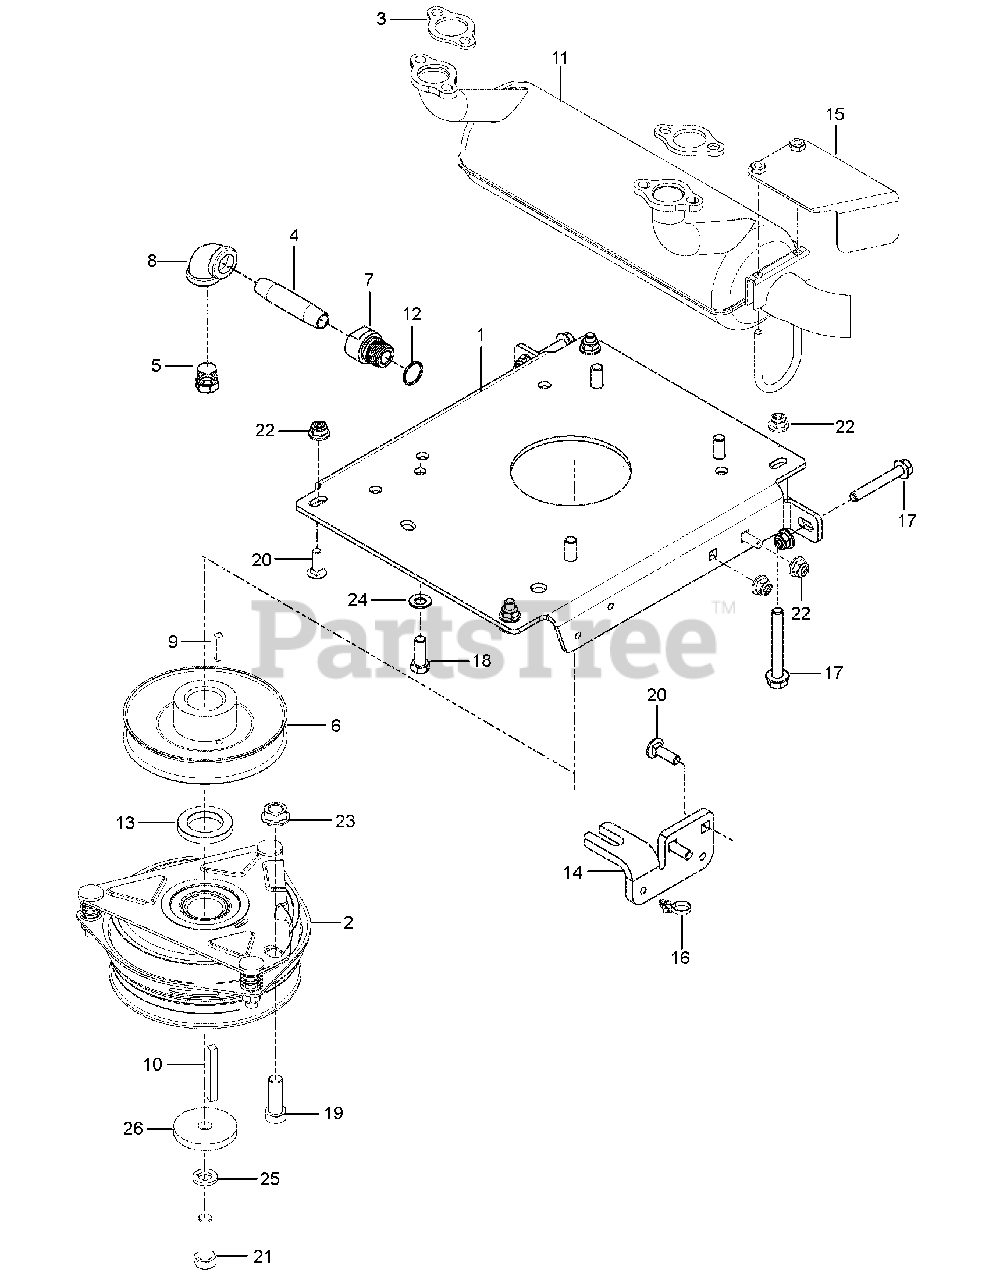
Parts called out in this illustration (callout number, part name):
1	PLATE.PNT.ENGINE.PZ/PZT.EDIP
2	CLUTCH, 150 FT/LBS
3	GASKET.EXHAUST.KAWASAKI
4	PIPE NIPPLE 3/8 X 3
5	PLUG, DRAIN 3/8 NPTF
6	PULLEY, ENGINE
7	ADAPTER, OIL DRAIN
8	90 DEG.ELBOW 3/8NPT
9	KEY 1/4 SQ X 1.0
10	KEY 1/4 SQ X 2
11	MUFFLER.26HP.KAW.FX651V-730V
13	SPACER, .25 X 1.135 I.D.
14	STOP, CLUTCH, OGURA
15	SHIELD MUFFLER
16	TIE WRAP, 8-3/8", W/CLIP
17	HHFS 5/16-18 X 2.25 GD 5
18	HCS 3/8-16X1.GRD.5.ZD
19	HCS 7/16-14 X 1-1/4 GR 5 ZD
20	RHSNB 5/16C X 1
21	CLUTCH BOLT7/16-20X1.5GR5.96HR
22	5/16-18 NYLOC FLANGE NUT
23	NUT 7/16C WHIZ
24	WASHER, 3/8 DISC SPRING SPEC
25	WASHER 7/16 LOCK
26	BLADE WASHER
